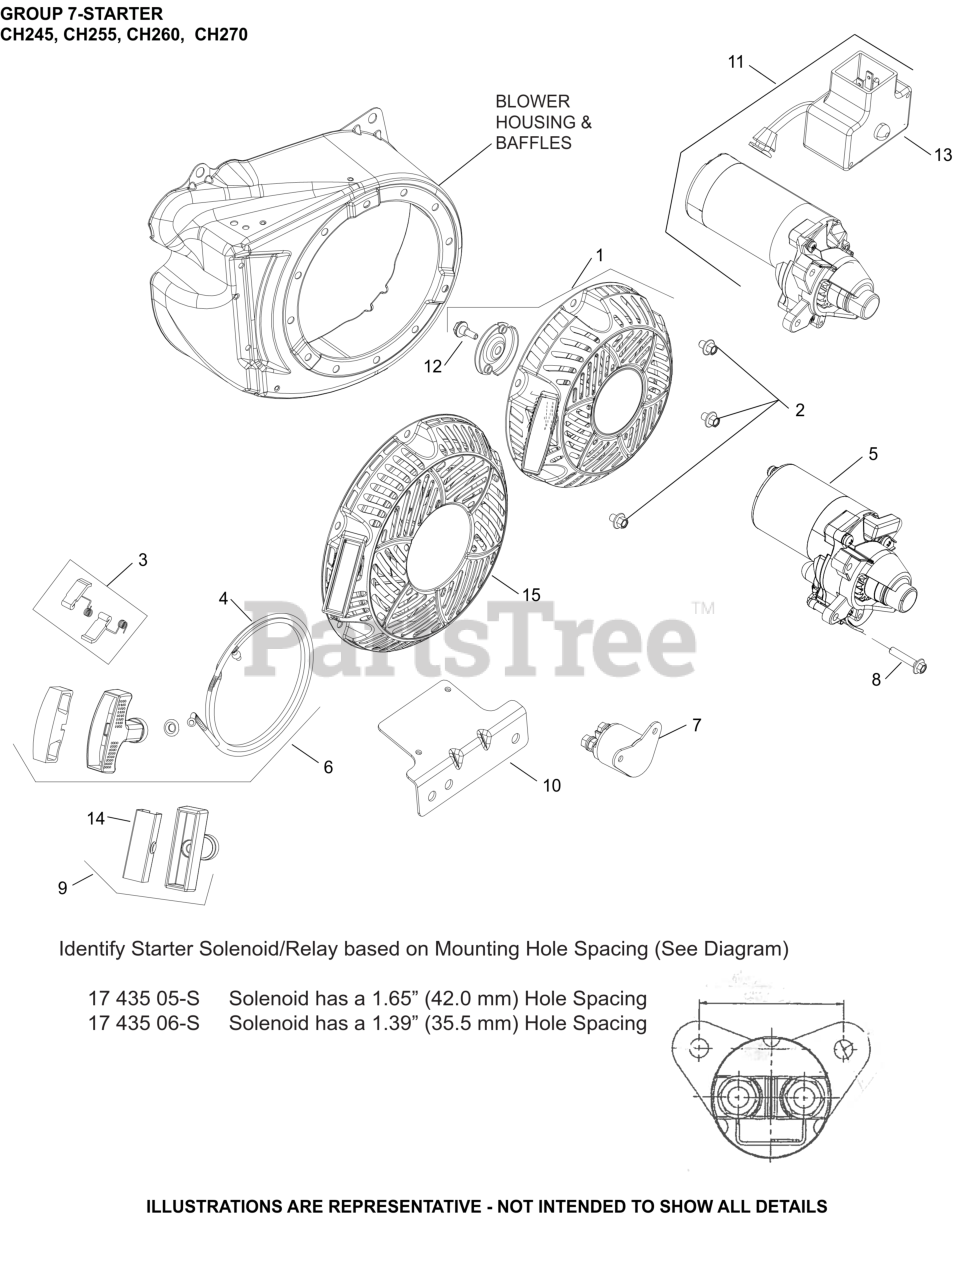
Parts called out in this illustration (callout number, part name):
1	STARTER ASSEMBLY, RETRACTABLE
2	SCREW, M6 X 8 HEX FLANGE HEAD
3	KIT, PAWL REPAIR
4	ROPE, STARTING
6	KIT, STARTER ROPE W/HANDLE
6	KIT, ROPE & HANDLE
12	SCREW, SHOULDER (M5)
